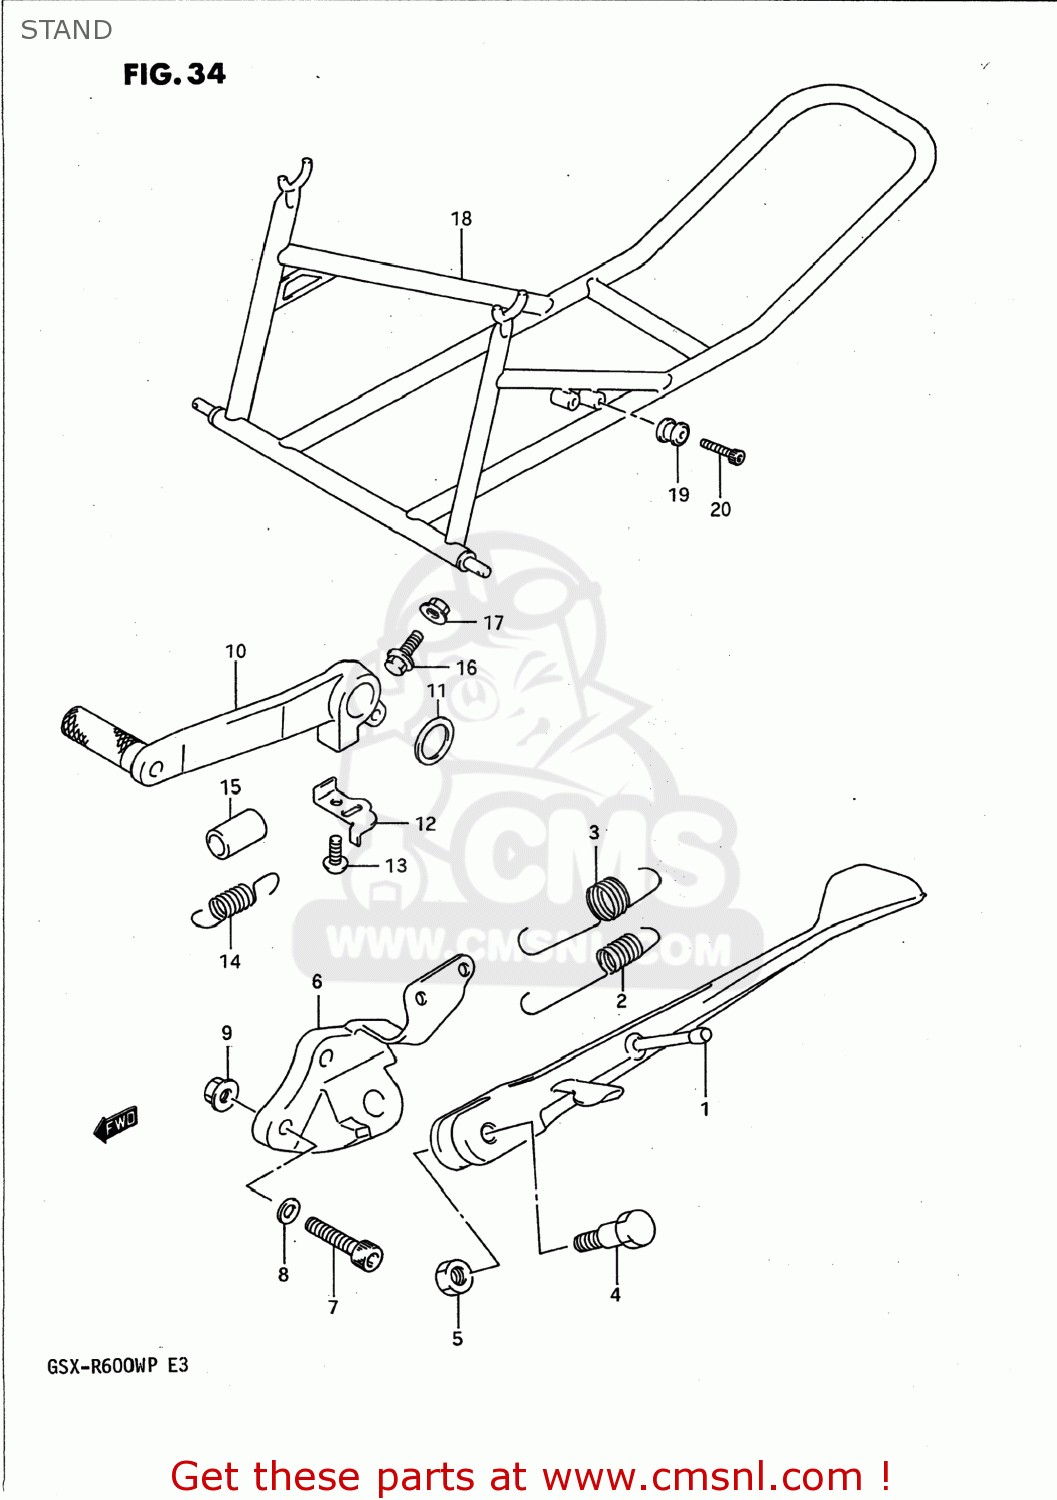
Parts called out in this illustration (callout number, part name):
1	STAND,PROP
2	SPRING
3	SPRING
4	BOLT(10X38)
5	NUT
6	BRACKET,PROP STAND
7	BOLT, FRONT RH
8	WASHER
9	NUT
10	PEDAL,BRAKE
11	WASHER(18X24X1)
12	HOOK,RETURN SPRING
13	SCREW(6X12)
14	SPRING
15	TUBE,BRAKE SPRING GUIDE
16	BOLT
17	NUT 5MM
18	STAND ASSEMBLY,REAR
19	HOLDER,STAND
20	BOLT, REAR (8X30)
